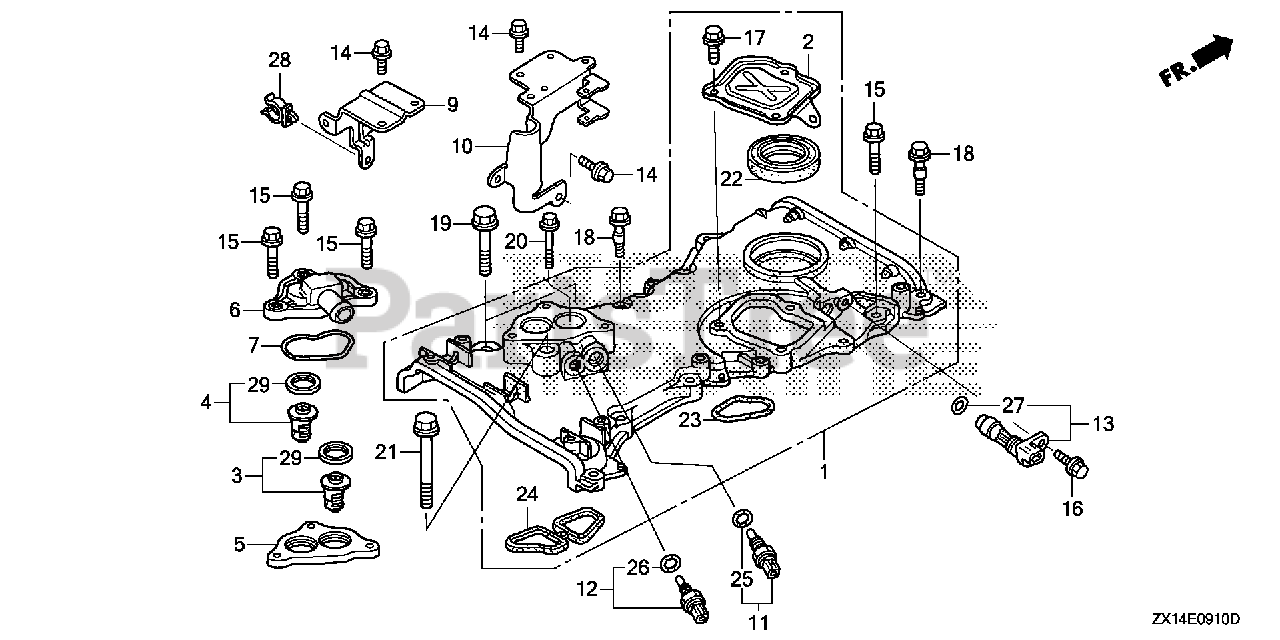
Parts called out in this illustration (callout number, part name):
1	CASE ASSY., CHAIN *NH8* (DARK GRAY)
2	COVER, CHAIN CASE
3	THERMOSTAT ASSY.
4	THERMOSTAT ASSY.
5	SPACER KIT, THERMOSTAT COVER
6	COVER, THERMOSTAT
7	GASKET, THERMOSTAT COVER
9	BRACKET B, HARNESS CLIP
10	BRACKET C, HARNESS CLIP
11	SENSOR ASSY., WATER TEMPERATURE
12	SENSOR ASSY., WATER TEMPERATURE
13	SENSOR ASSY., CRANK
14	BOLT, FLANGE (6X14) (CT200)
15	BOLT, FLANGE (6X28)
16	BOLT, FLANGE (6X16)
17	BOLT, FLANGE (6X14)
18	BOLT, SPECIAL (6X31)
19	BOLT, FLANGE (10X43)
20	BOLT, FLANGE (6X38)
21	BOLT, FLANGE (10X70)
22	OIL SEAL (43X58X7) (ARAI)
23	O-RING, CHAIN CASE
24	GASKET, CHAIN CASE
25	O-RING (9.5X1.5) (HONDA KIKAKI)
26	O-RING (9.5X1.9)
27	O-RING (15X1.9)
28	CLAMP (18.5MM)
29	RUBBER, RING
30	CASE KIT, CHAIN
32	SUB-WIRE HARNESS ASSY. (B)
33	BRACKET, SUB-HARNESS CLIP
35	CLIP, HARNESS BAND (145MM) (BLACK)
